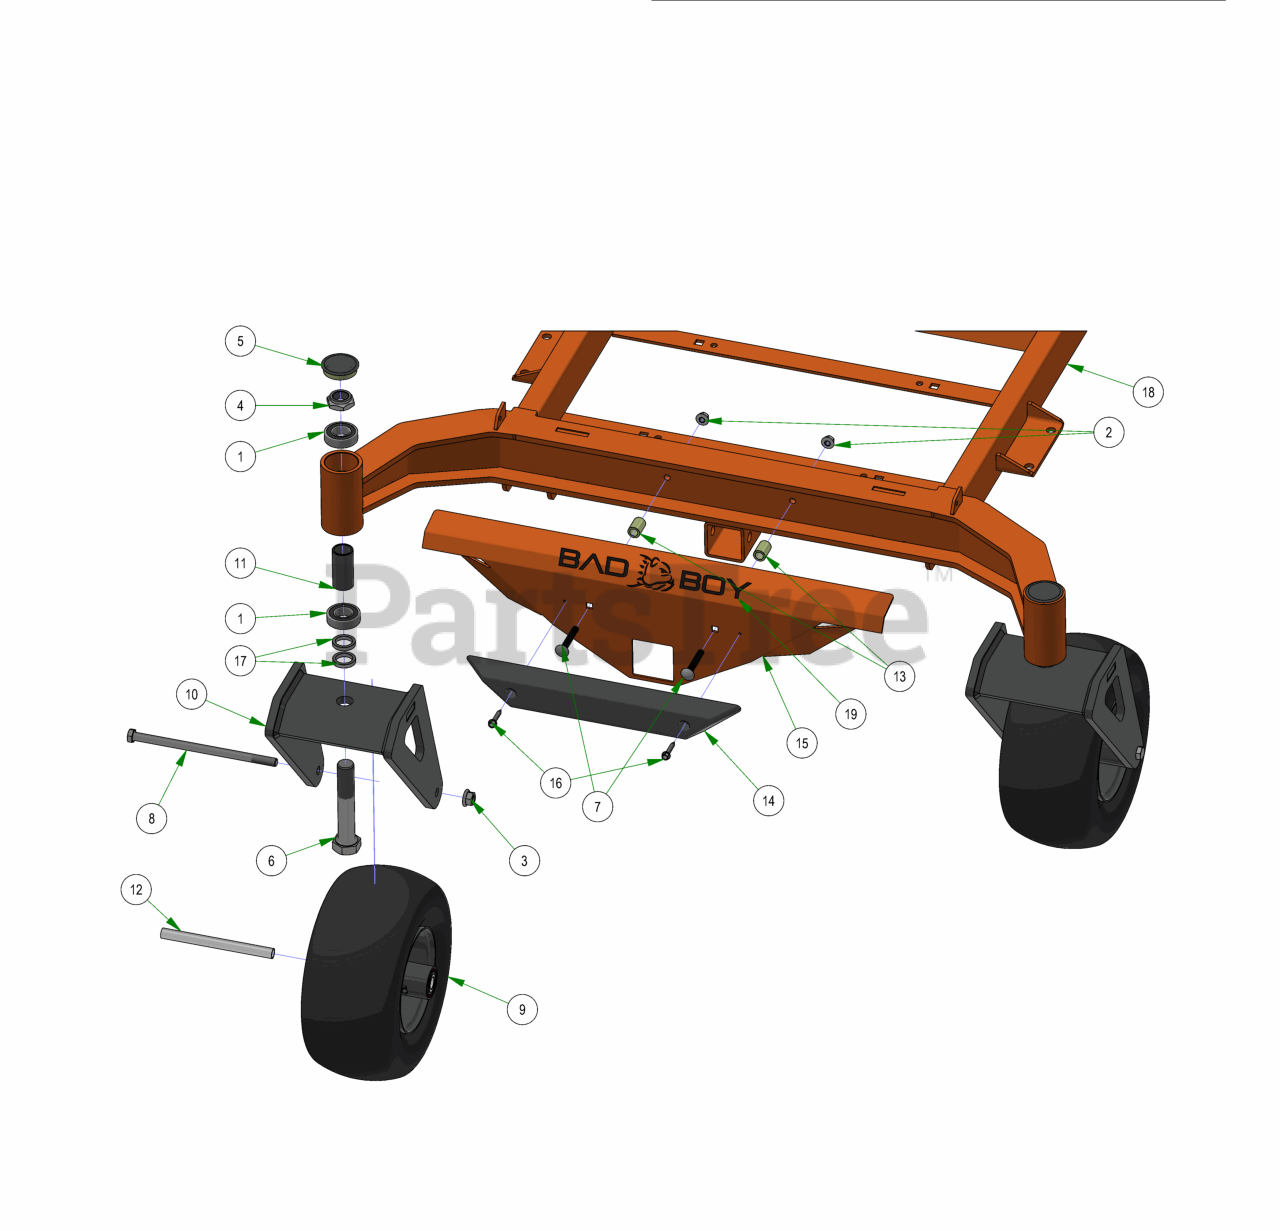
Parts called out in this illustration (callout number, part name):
1	1641 BEARING W/2 CONTACT RUBBER SEALS
2	3/8-16 NYLON INSERT FLANGE LOCKNUT (GR.F) ZINC
3	1/2-13 NYLON INSERT FLANGE LOCKNUT ZINC
4	1"-14 NYLON INSERT JAM LOCKNUT ZINC
5	2017 Bearing Cover
6	1"-14 X 5-1/2 HEX CAP SCREW (GR.8) ZINC YELLOW
7	3/8" x 2 1/2" Carriage Bolt
8	1/2-13 X 9 HEX CAP SCREW (GR.5) ZINC
9	13x6.50-6 Black No Flat Assembly
10	2019 Rebel Front Fork - Weldment - Black
11	2016 Front Bearing Spacer
12	Front Wheel Spanner
14	2017 XP BUMPER
15	2024 Rebel Front Bumper Plate
16	1/4-14 X 1-1/2 HEX WASHER UNSLOT TEK/3 ZINC
17	1.02 ID X 1.38 OD X .250 THK SPACER ZINC
18	2023 Rebel Frame - Painted
19	Flying Bulldog Front Bumper Decal
